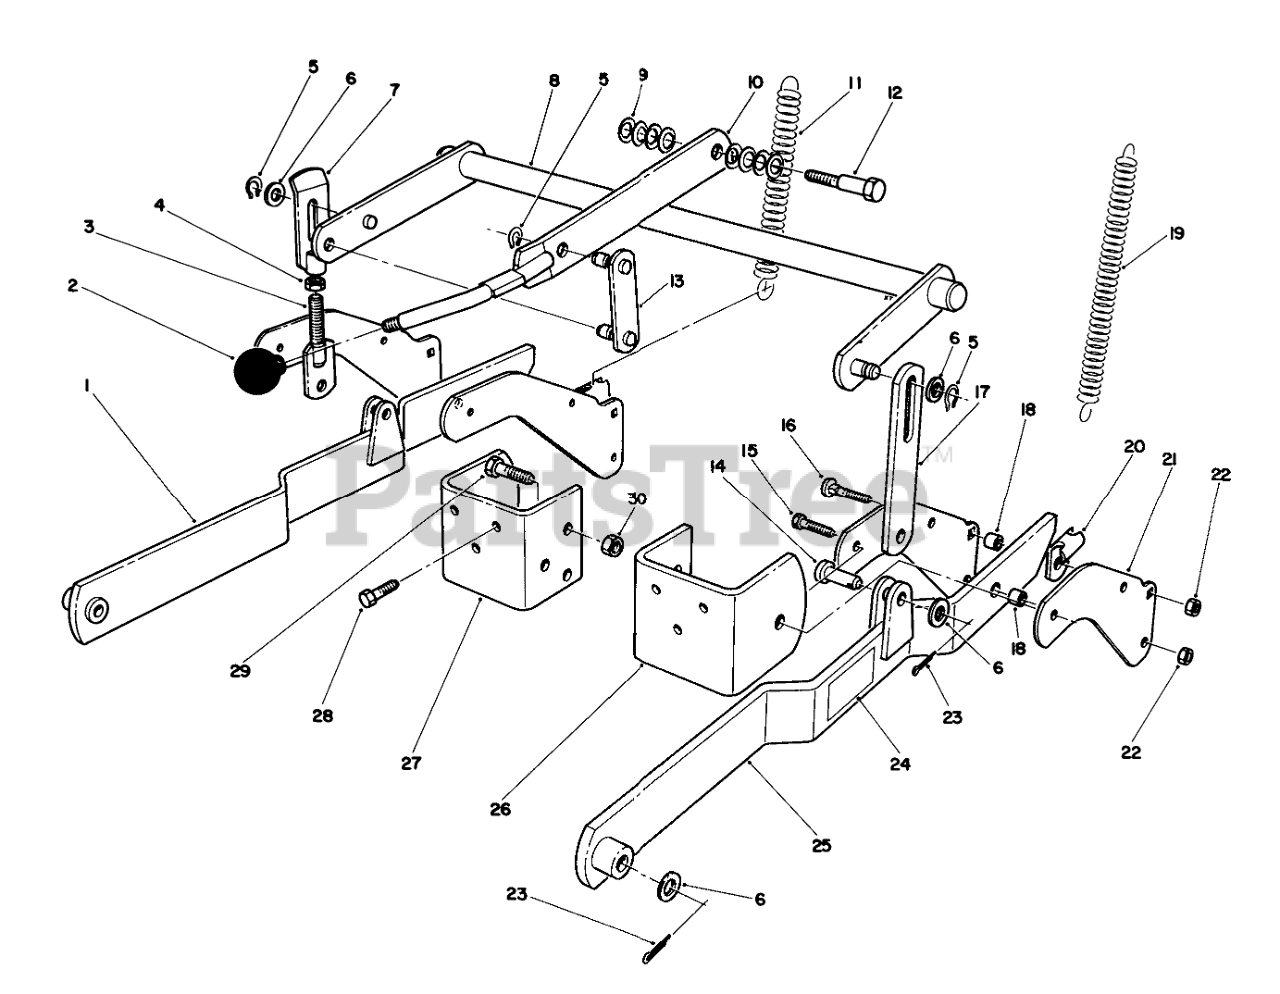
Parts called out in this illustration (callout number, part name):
1	Lift Bar-R.H. (Incl. Ref. #24)
3	HOC PLATE WA
4	NUT-JAM
5	RING-RETAINING
6	WASHER-FLAT
7	HOC LINK WA
8	HOC PIVOT ARM WA B
9	WASHER-BELLEVILLE
10	HOC LEVER WA B
11	SPRING
12	BOLT-SHOULDER
13	UPPER HOC LINK WA
14	PIN-CLEVIS
15	SCREW-HH
16	SCREW-CARR
17	SUSPENSION DECK LINK B
18	DECK LIFT SPACER
19	EXTENSION SPRING
20	DECK SPRING LINK
21	REAR PIVOT ARM B
22	NUT-LOCK, NI
23	PIN-COTTER
24	DECAL-WARNING
25	Lift Bar-L.H. (Incl. Ref. #24)
26	U-BRKT DECK LIFT B
27	U-BRKT DECK LIFT B
28	SCREW-HH
29	SCREW-HH
30	NUT-LOCK, NI
